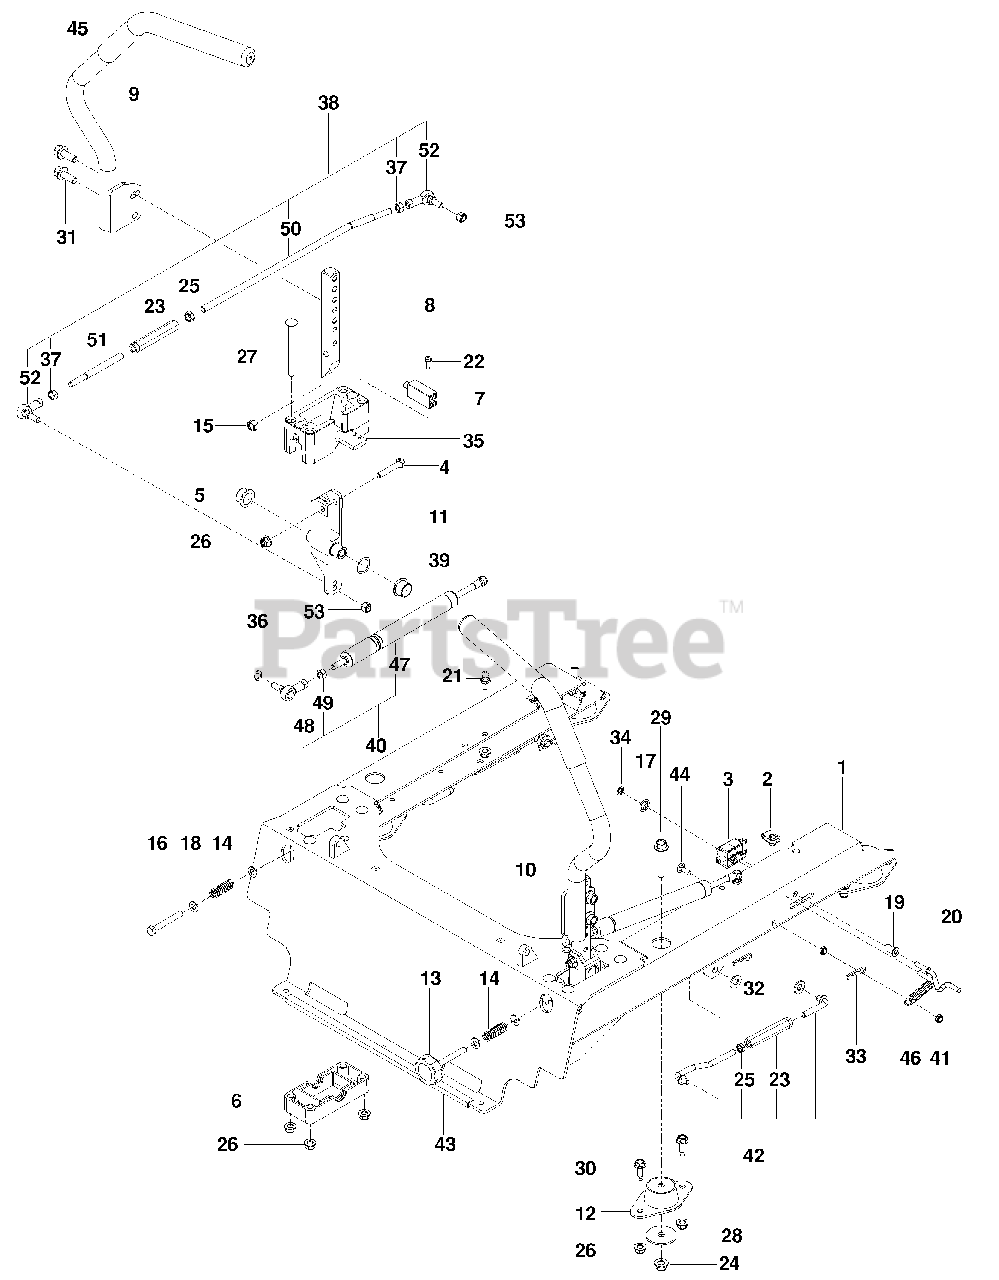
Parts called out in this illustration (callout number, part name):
1	Frame Mount
2	Retainer, U Type
3	Switch, Brake (3-Pole)
4	Bolt 5/16-18 X 1 3/4 Hex Nyl
5	Bearing, Flange
6	Block, Lower
7	Switch N.C.
8	Lever, Motion
9	Lever W/ Grip Rt
10	Lever W/ Grip Lt
11	Lever, Control
12	Mount, Iso
15	Nut 5/16-18 Hex
16	Bolt 5/16-18 X 2 1/2 Hex Tpblt
17	Retainer Nut 3/8
18	Washer 5/16 Sae Flat
19	Bushing 1/4 Flange
20	Link, Switch
21	Ball Stud 10Mm
22	Screw 10-24 X 5/8 Washer Hd
23	Turnbuckle 3/8
24	Nut 3/8-16 Hex Flg Nyloc
25	Nut 3/8-24 Hex Jam
26	Nut 5/16-18 Hex Flange Nyloc
27	Bolt 5/16-18 X 3 3/4 Rd Hd
28	Washer 3/8 Special
29	Hhfs 3/8-16 X 2
30	Hhfs 5/16-18 X 3/4
31	Screw 3/8-16 X 1 Hex Flg
32	Washer 3/8 Sae Flt
33	Hairpin Cotter
34	Push Nut 1/4
35	Block, Upper
36	SCREW 3/8-16 x 1 1/2 HEX HD
37	Nut 5/16-24 Hex
38	Linkage Control Assy
39	Washer, Wave
40	Dampener Assy
41	Nut 1/4-20 Hex Thin Nyloc
42	Seat Strut Assy
43	Flex Trim Blk
44	Bolt 1/4-20 X 3/4 Gr2 Rd Hd
45	Grip, Lever
46	Spring
48	Rod End, Spherical
49	Hexnut M8 X 1.25 Std
50	Linkage, Control Ft
51	Linkage, Control
52	Rod End, Spherical Rh
53	Nut 5/16-24 Nyloc
